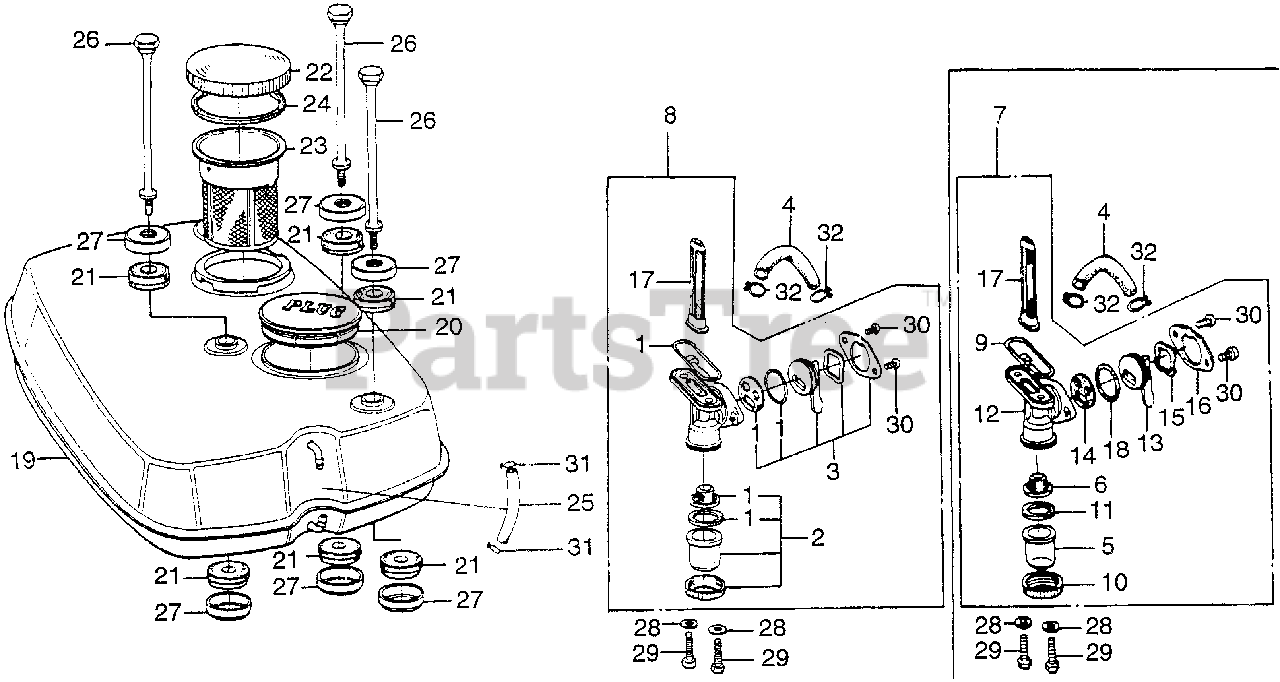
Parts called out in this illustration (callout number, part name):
1	GASKET SET, VALVE (NOT AVAILABLE)
2	CAP SET, STRAINER
3	LEVER SET, VALVE (NOT AVAILABLE)
4	TUBE, FUEL
8	PETCOCK ASSY.
19	TANK, FUEL *NH31* (MCKINLEY WHITE)
20	COVER, PLUG *Y3L* (IVORY WHITE) (NOT AVAILABLE)
21	RUBBER, TANK CUSHION (NOT AVAILABLE)
22	CAP, FUEL TANK (NOT AVAILABLE)
23	FILTER, FUEL
24	GASKET, FUEL FILTER (NOT AVAILABLE)
26	BOLT, TANK SETTING
27	WASHER, TANK (NOT AVAILABLE)
28	GASKET, FIBER (6MM)
29	SCREW, PAN (6X16)
30	SCREW, PAN (3X6)
31	CLIP, TUBE (C9)
32	CLIP, TUBE (B12)
